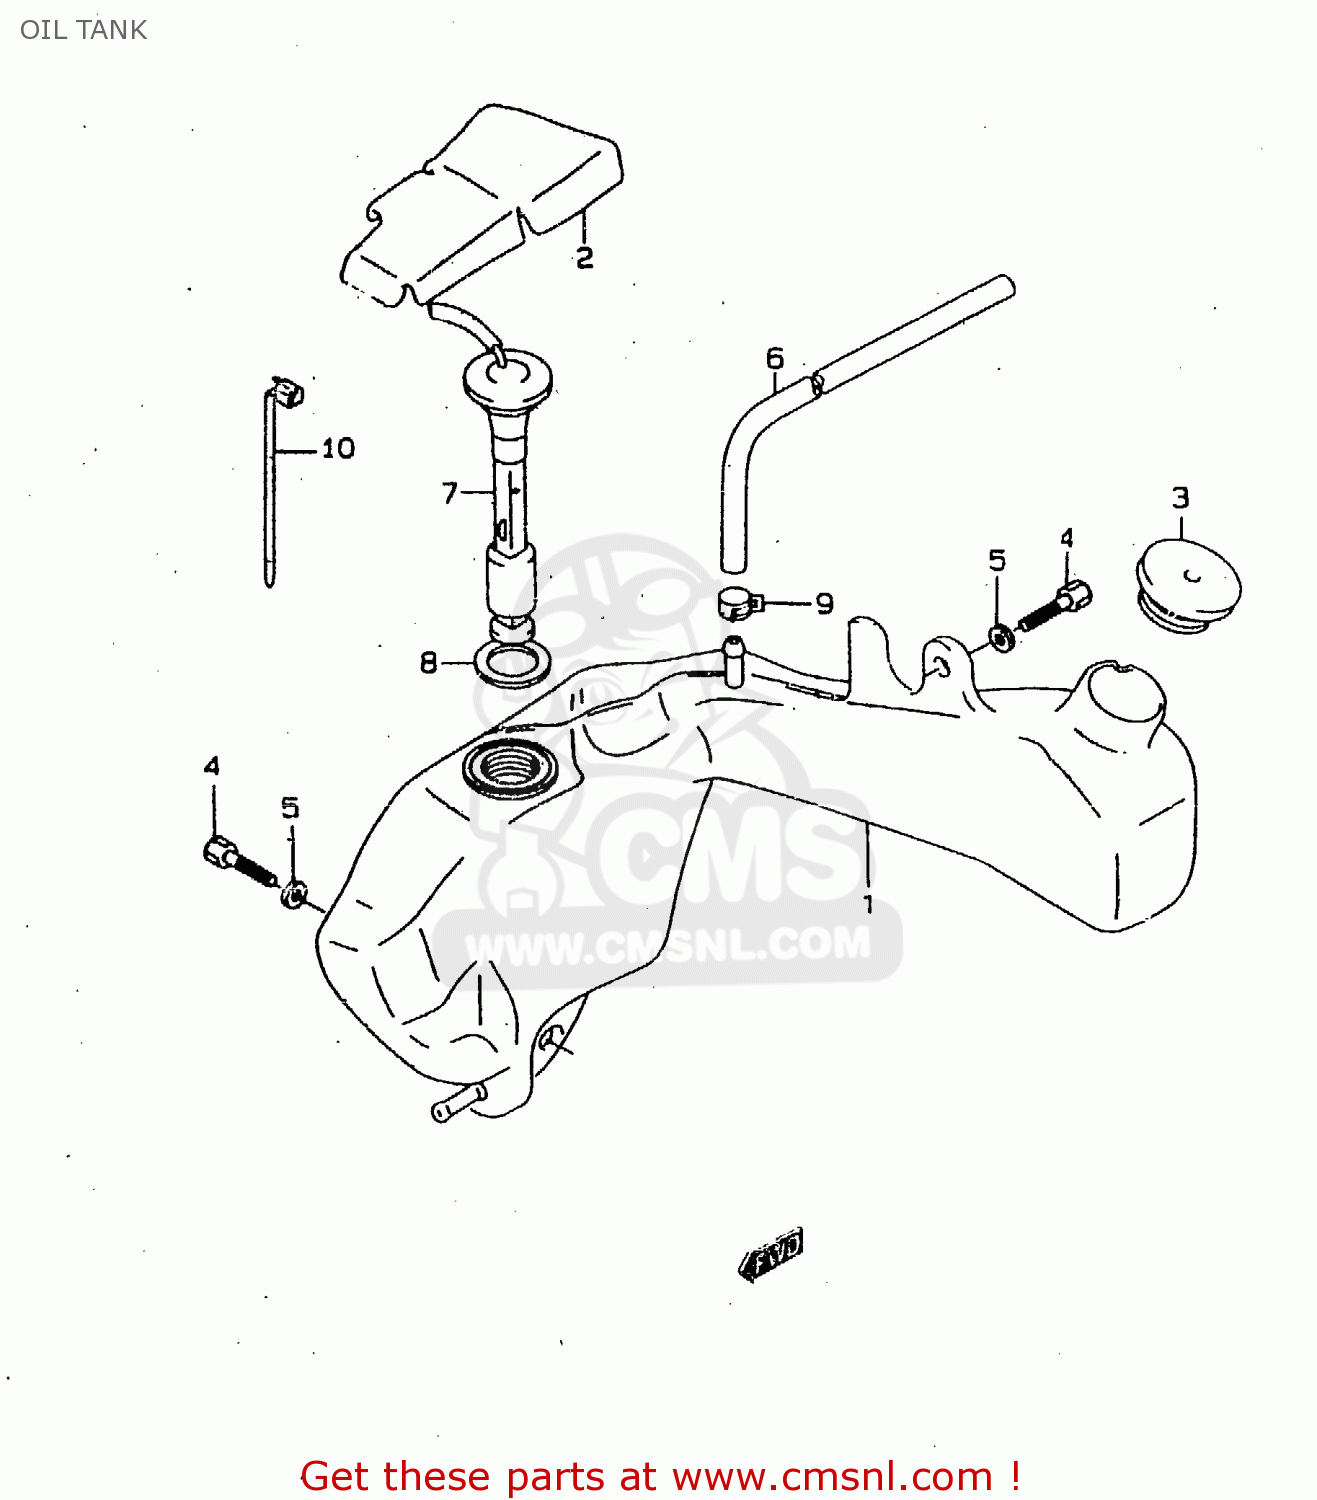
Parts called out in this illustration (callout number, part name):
1	TANK,OIL
2	SHIELD, OIL TANK
3	CAP,OIL TANK
4	BOLT,OIL FILLE
5	WASHER(6.5X18X1.6)
6	HOSE(7X10.2X600)
7	SWITCH ASSY,OIL LEVEL
8	GASKET (NAS)
9	CLAMP
10	CLAMP(L:125)
